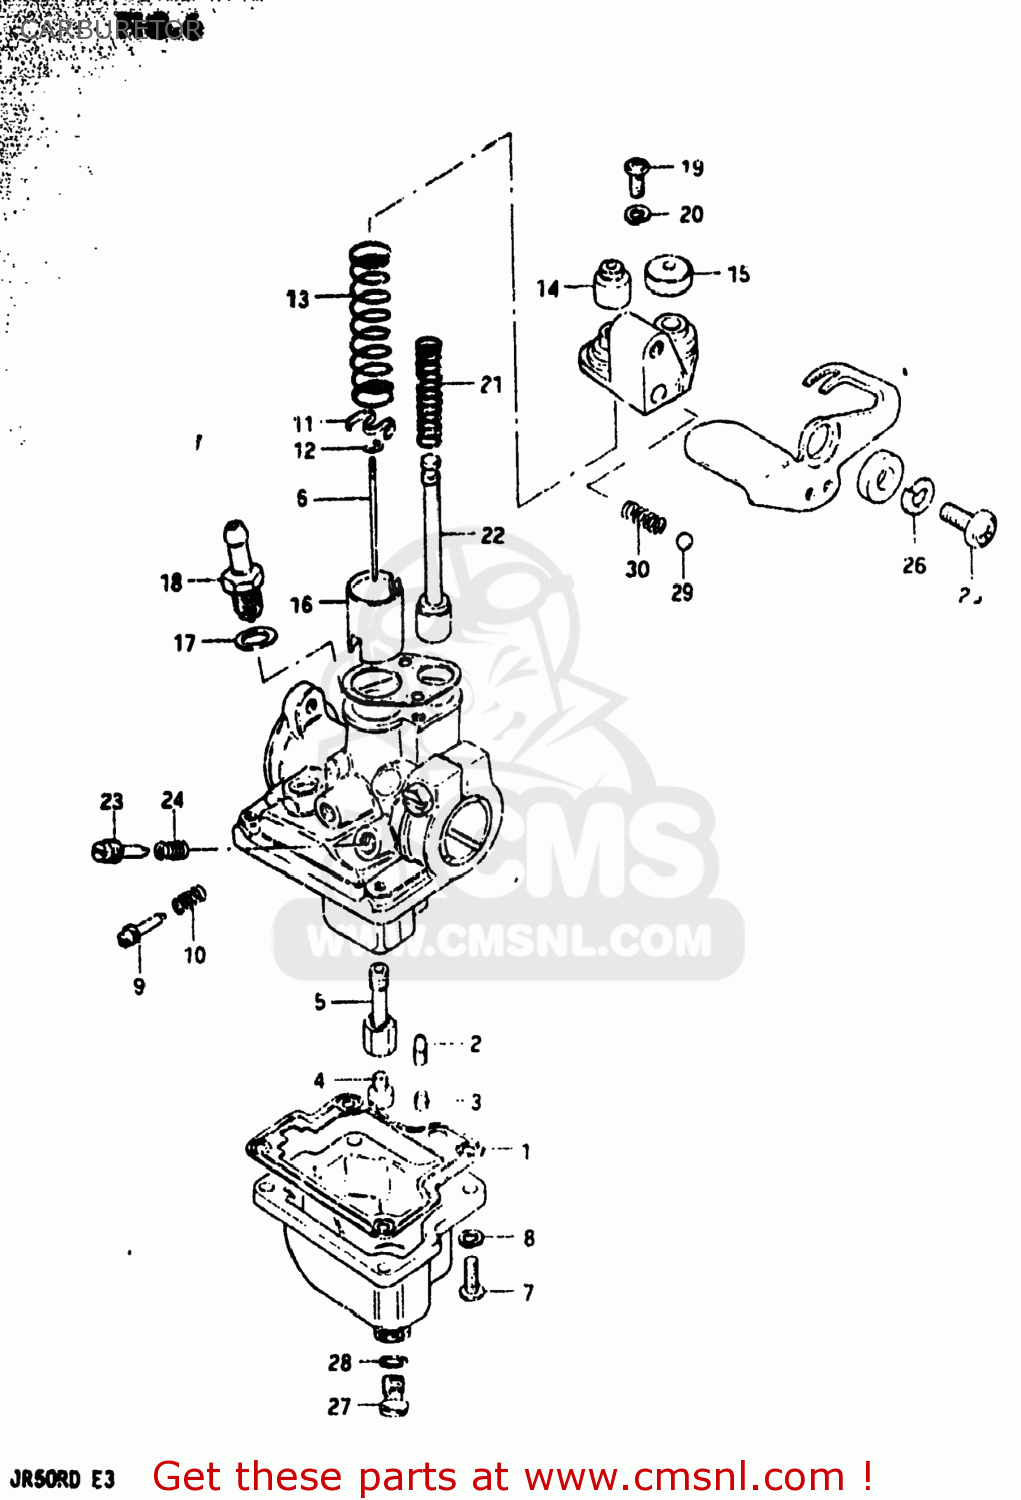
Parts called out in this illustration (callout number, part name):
1	GASKET,FLOAT CAHMBER (NAS)
2	JET,PILOT
3	JET,PILOT
4	JET,MAIN(57.5)
5	JET,NEEDLE
6	NEEDLE,JET
7	SCREW
8	LOCK WASHER
9	SCREW,THROTTLE STOP
10	SPRING
11	SEAT,THROTTLE VALVE SPRING
12	CLIP,NEEDLE
13	SPRING,THROTTLE VALVE
14	CAP
15	RUBBER,THROTTLE VALVE CAP
16	VALVE,THROTTLE
17	GASKET (NAS)
18	VALVE ASSY,NEEDLE
19	SCREW 4X10
20	LOCK WASHER
21	SPRING
22	VALVE,STARTER
23	SCREW,AIR
24	SPRING
25	SCREW 6X12
26	LOCK WASHER
27	PLUG
28	GASKET,DRAIN,PLUG (NAS)
29	BALL,STARTER SHAFT
30	SPRING,STARTER SHAFT
